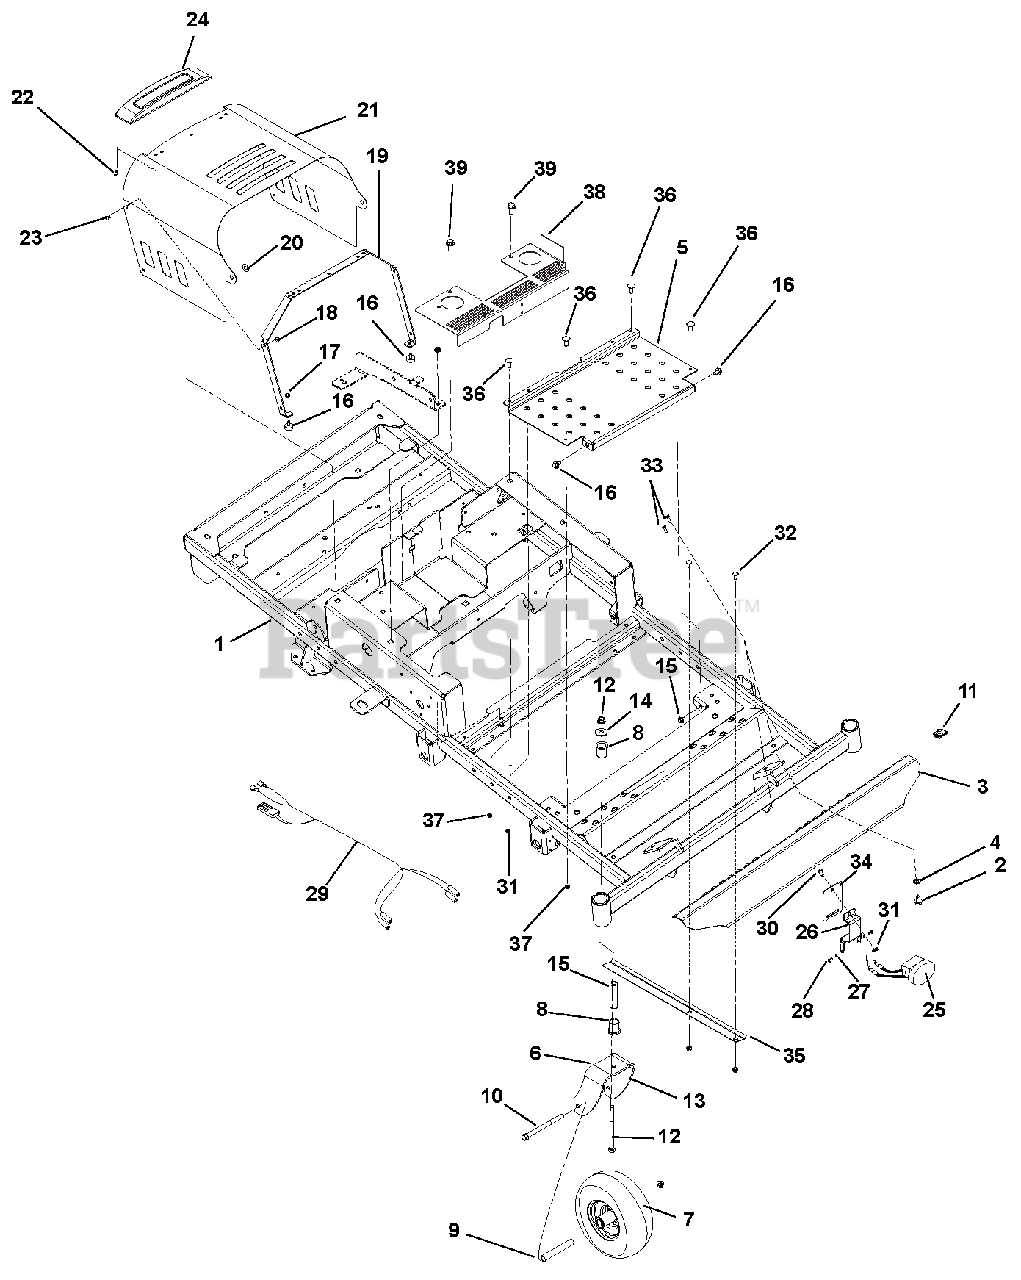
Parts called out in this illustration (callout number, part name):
1	WLDMT, FRAME ZT/ZOOMXL (2013)
2	@BLT-HEX .38-16X1.00 GR5 YWZC
3	WMT, FOOTREST
4	@WSHR-LK .38X.094 REG YWZC
5	PANEL WLDMT, FOOT PLATE
6	WMT, CASTER FORK
7	TIRE/WHEEL ASSY, 11X4-5
8	BSHG-FLG 1.00X1.25X1.50X1.50EP
9	SPACER, ROLLED WHEEL
10	@BLT-HEX .50-13X6.50 GR5 YWZC
11	NUT-RTNR .375-16X.37
12	@NUT-LK-TOP-FLG .50-13 YWZC
13	@BLT-HEX .50-13X5.00 GR5 YWZC
14	WSHR-FL-STL.511X1.441X.125 YWZ
15	SPACER, CASTER FORK
16	BUMPER, RUBBER
17	@NUT-SPNLK-FLG .312-18 YWZC
18	@NUT-LK-TOP-FLG .25-20 YWZC
19	HOOD STRAP
20	WSHR-FL-NYL .518X1.000X.080
21	HOOD, XL
22	SCR-.25X.62 PN HD BOSSSCREW YZ
23	@BLT-RDHDSQNK .25-20X.50 G5YZ
24	TRIM-ZOOM XL HOOD ARIENS
25	KIT, ZOOM/ZT XL LIGHT
26	BRKT, LIGHT MOUNT
27	WSHR-LK 4MMX1MM REG CL ZINC
28	SCREW-M4X.07X8 SHCS CLZNC
29	HARNESS, XL HEADLIGHT
30	@BLT-RDHDSQNK .25-20X.75 G5YZ
31	@NUT-LK-TOP-FLG .25-20 YWZC
32	@BLT-RDHDSQNK .31-18X.75 G5YZ
33	@BLT-HEX .25-20X.75 GR5 YWZC
34	BRKT, LIGHT FRAME MOUNT
35	BRACKET, LIGHT HARNESS
36	@BLT-HEX .31-18X1.00 GR5 YWZC
37	@NUT-LK-NYL-FLG .31-18 YWZC
38	BRACKET, XL CE FAN GUARD
39	@SCR-TAP .38-16X.50 HWH TR YWZ
